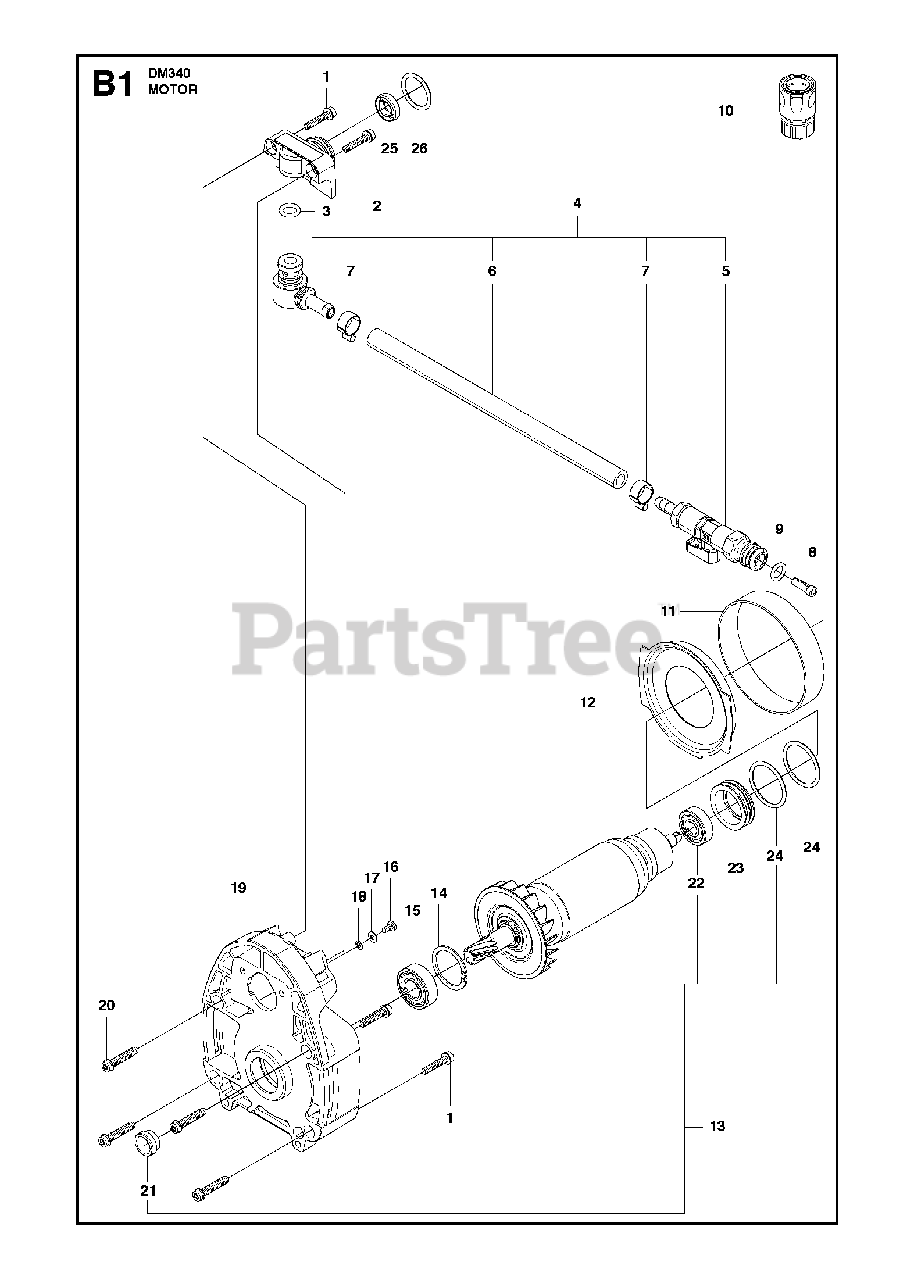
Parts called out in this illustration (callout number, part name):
1	SCREW IHSCFM
10	COUPLERUS, CANADA
15	BALL BEARING
